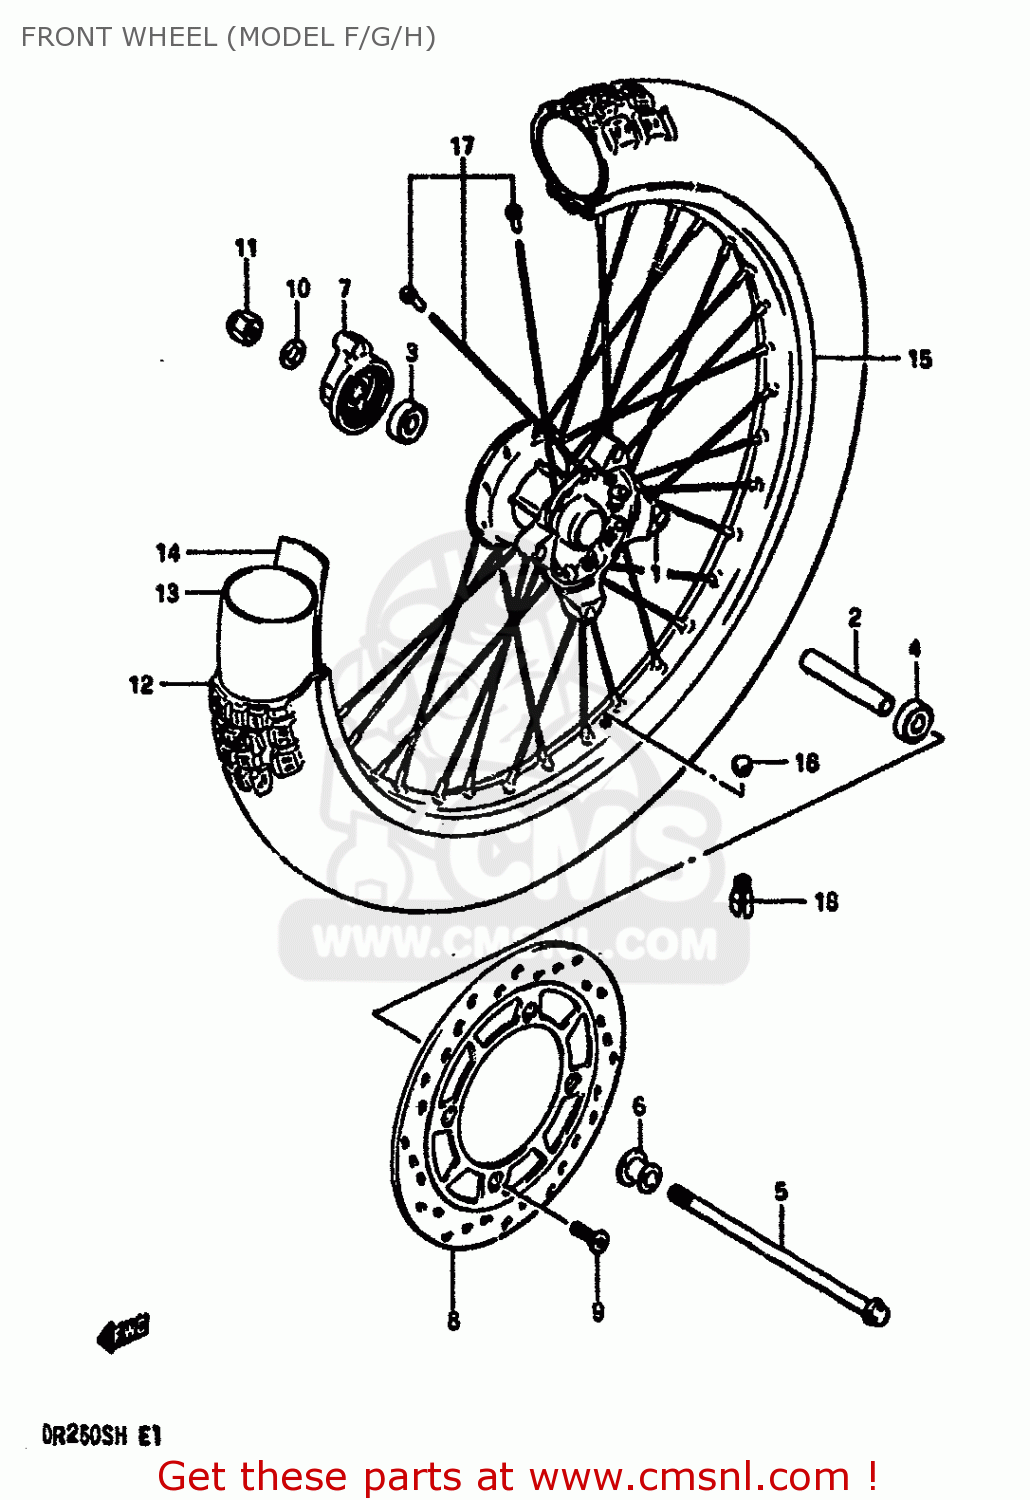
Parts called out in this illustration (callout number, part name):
1	HUB,FRONT
2	SPACER (12.6X19X60.5)
3	BEARING
4	BEARING, RH
5	AXLE,FRONT
6	SPACER,FRONT AXLE,RIGHT
7	BOX ASSY,SPEEDOMETER GEAR
8	DISC,FR BRAKE
9	BOLT,BRAKE DISC
10	WASHER
11	NUT 12MM
12	TIRE,FRONT
13	TUBE
14	PROTECTOR,WHEEL,INNER
15	RIM,FRONT WHEEL
16	CAP(OD:12)
17	SPOKE SET,FRONT
18	BALANCER,WHEEL (50G)
